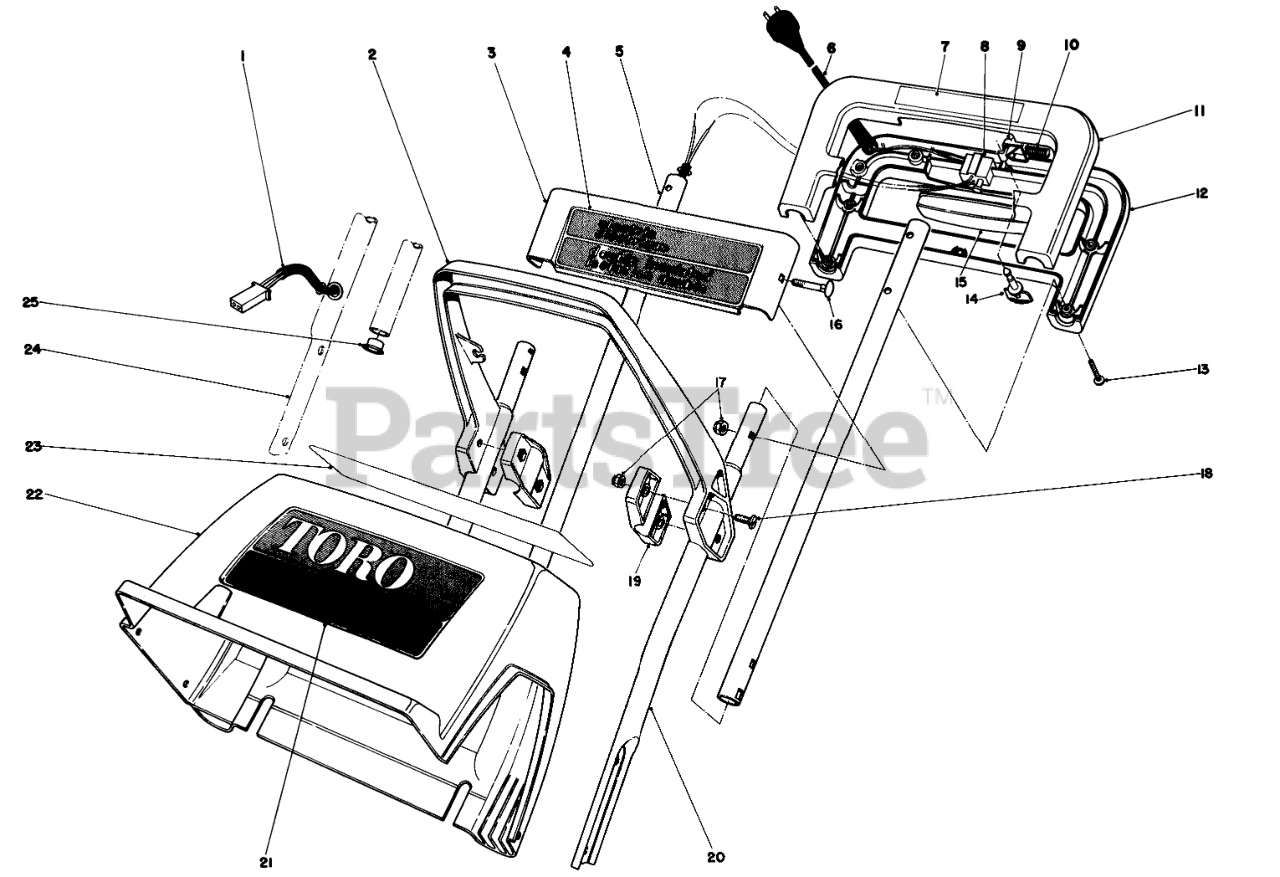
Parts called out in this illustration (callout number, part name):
1	Wire Harness
2	Middle Handle
3	Escutcheon Plate
4	Decal-Electric
5	UPPER TUBE, S-120
6	Cord Supply
7	Decal-Handle
8	SWITCH-STARTER
9	LOCKOUT, 1200
10	COMP SPRING
11	UPPER CONTRL HANDL HID
12	LOWR CONTRL HANDL HID
13	Screw
15	SWITCH BAR, 1200 PC
16	Bolt-Carriage
17	NUT-LOCK, NI
19	Clamp-Middle Handle
20	LOWER TUBE, LH, S-120
21	Decal-Toro S-120
22	Shroud S-120
23	Decal-U.L
24	LOWER TUBE, RH
25	SNAP BUSHING
